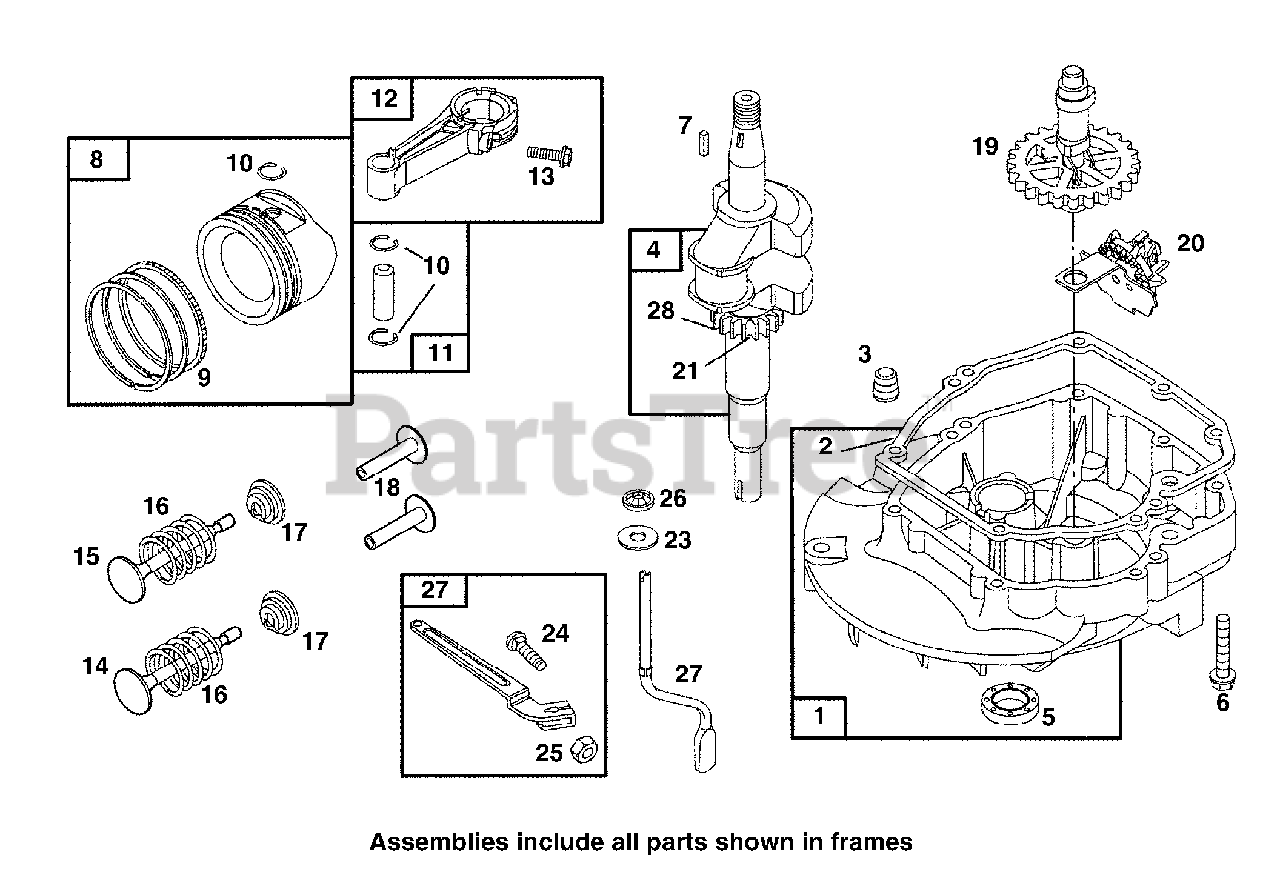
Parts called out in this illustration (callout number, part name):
1	Engine Sump
2	Crankcase Gasket
3	Oil Drain Plug
4	Crankshaft
5	Oil Seal
6	Hex Screw
7	Flywheel Key
8	Piston Assembly (Standard)
9	Ring Set (Standard)
10	Piston Pin Lock
11	Piston Pin (Standard)
12	Connecting Rod
13	Connecting Rod Screw
14	Exhaust Valve
15	Intake Valve
16	Valve Spring
17	Valve Retainer
18	Valve Tappet
19	Cam Gear
20	Governor/Oil Slinger
21	Timing Key
23	Flat Washer
24	Governor Lever Bolt
26	Governor Shaft Retainer
27	Governor Crank
28	Timing Gear
